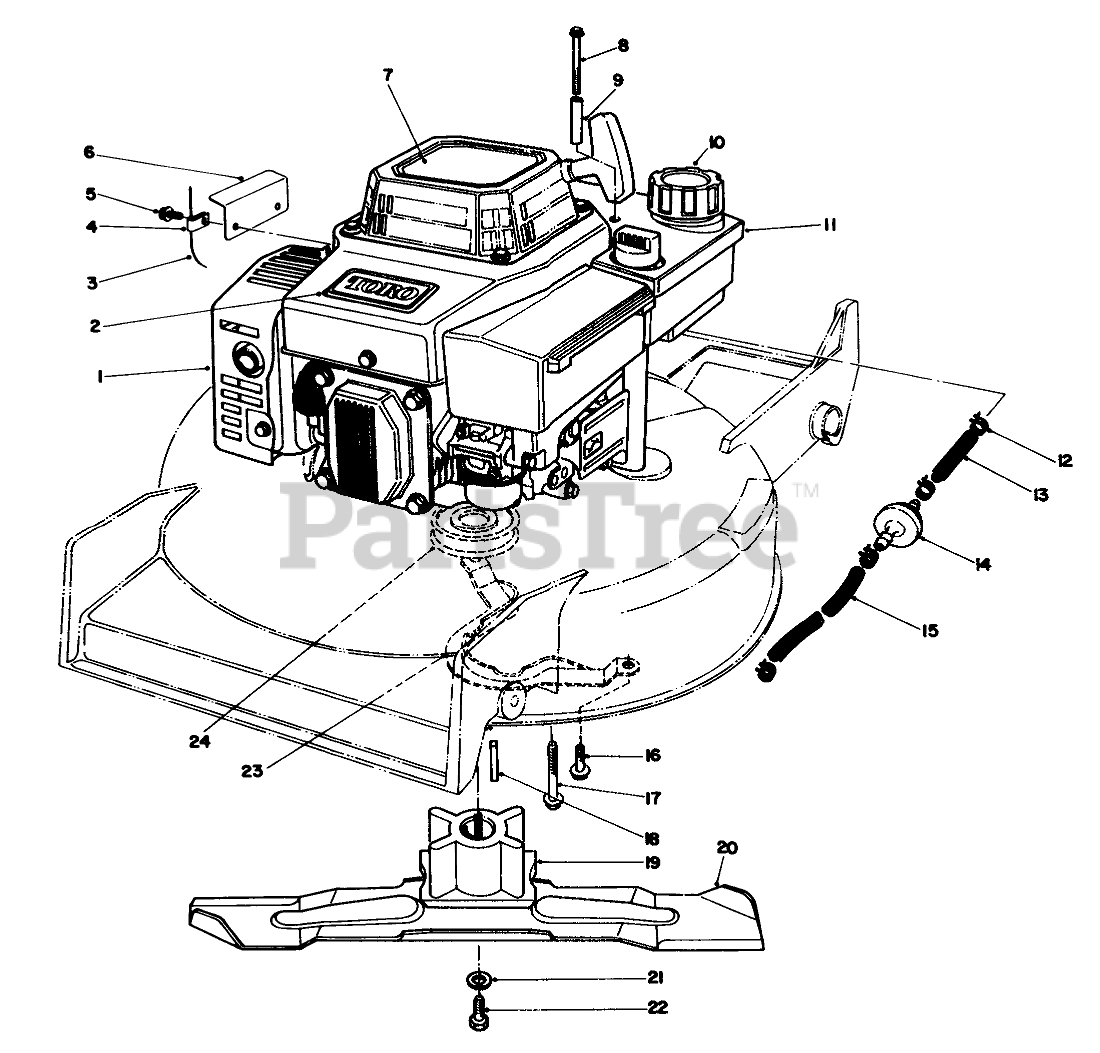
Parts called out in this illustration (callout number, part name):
2	TORO LOGO PLT
3	Wire Assembly
4	CLAMP-CABLE
5	THO FORM SCREW M6 X 1
6	FLYWHEEL SHIELD
7	DECAL-HV INT'L
8	THRD FORMING SCREW
9	TUBULAR SPACER
10	GAS CAP ASM
11	TANK ASM
12	CLAMP-FUEL LINE
13	LINE-GAS
14	FILTER-FUEL
15	HOSE-FUEL
16	Screw
17	SCREW-HWHTF
18	KEY-SQUARE
19	Retainer Blade
20	BLADE-21in
21	WASHER-LOCK
22	SCREW-BLADE
23	BELT GUIDE
24	PULLEY-DRIVER
